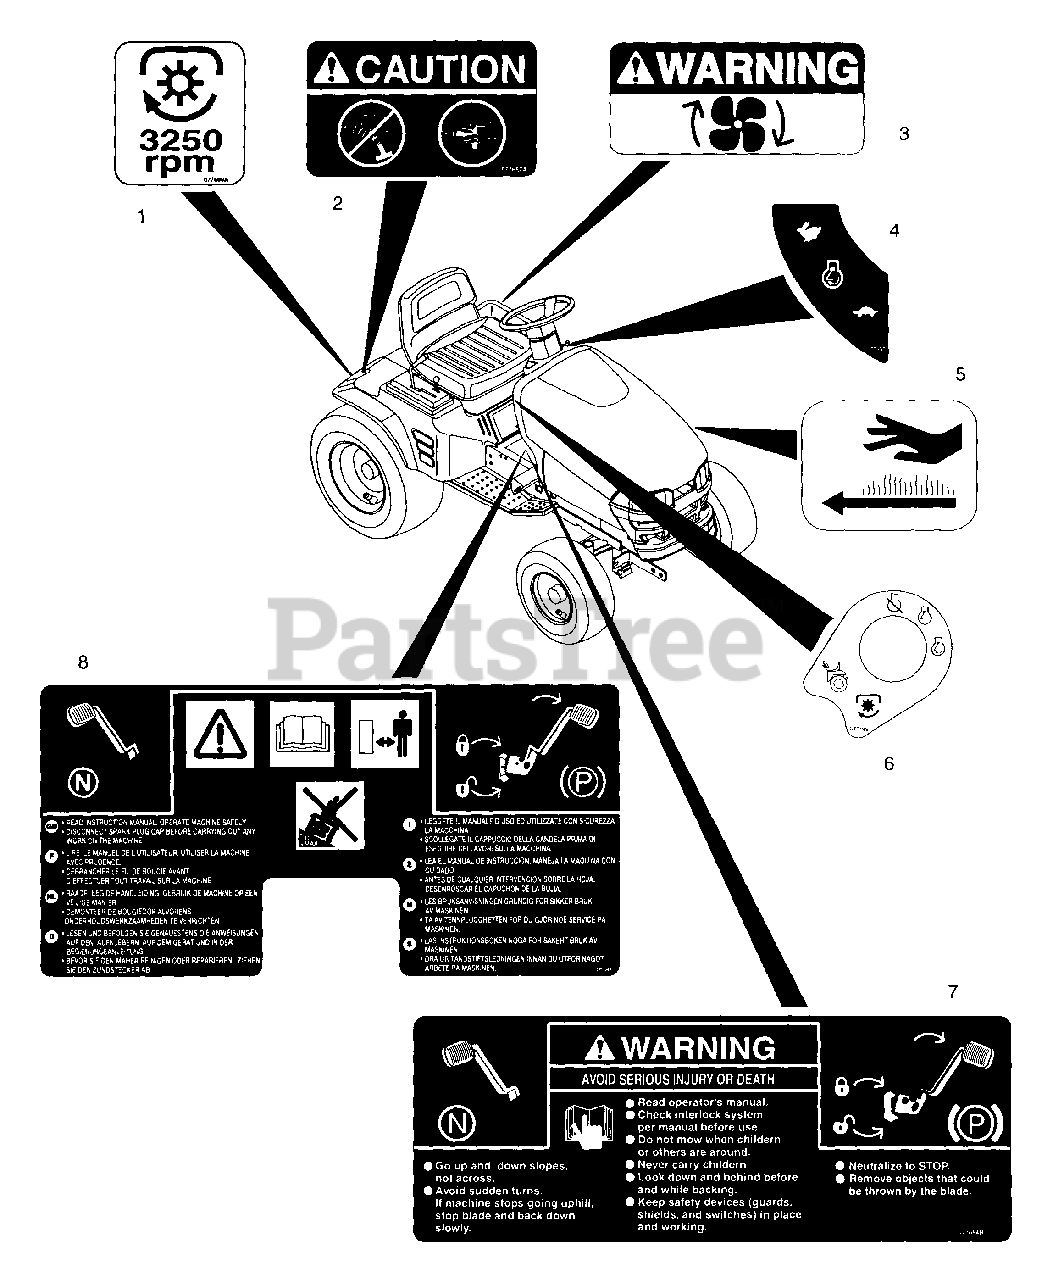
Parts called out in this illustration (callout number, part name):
1	DECAL - PTO SPEED
2	DECAL - CAUTION
3	DECAL - WARNING, FAN
4	DECAL- THROTTLE W/O CHOKE
5	DECAL- HOT SURFACE SYMB.
6	DECAL - IGNITION/PTO
7	DECAL - WARNING, INSTRUCTION
8	DECAL - WARNING INSTRUCTION
